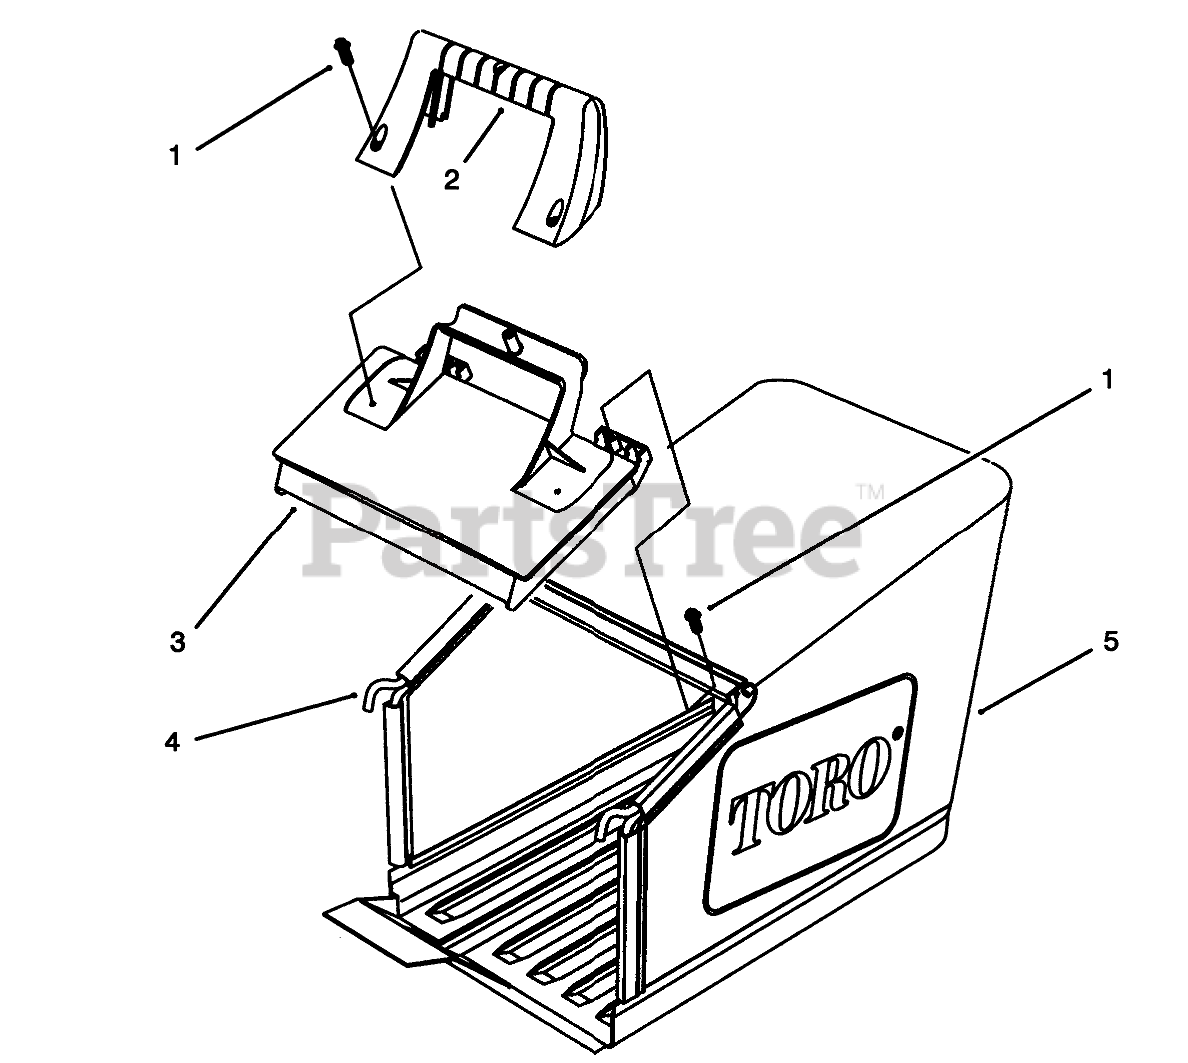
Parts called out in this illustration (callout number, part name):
1	SCREW-PPH
2	HANDLE-DOOR
3	DOOR-BAG
4	Frame
5	GRASS BAG 48CM W/PAN
